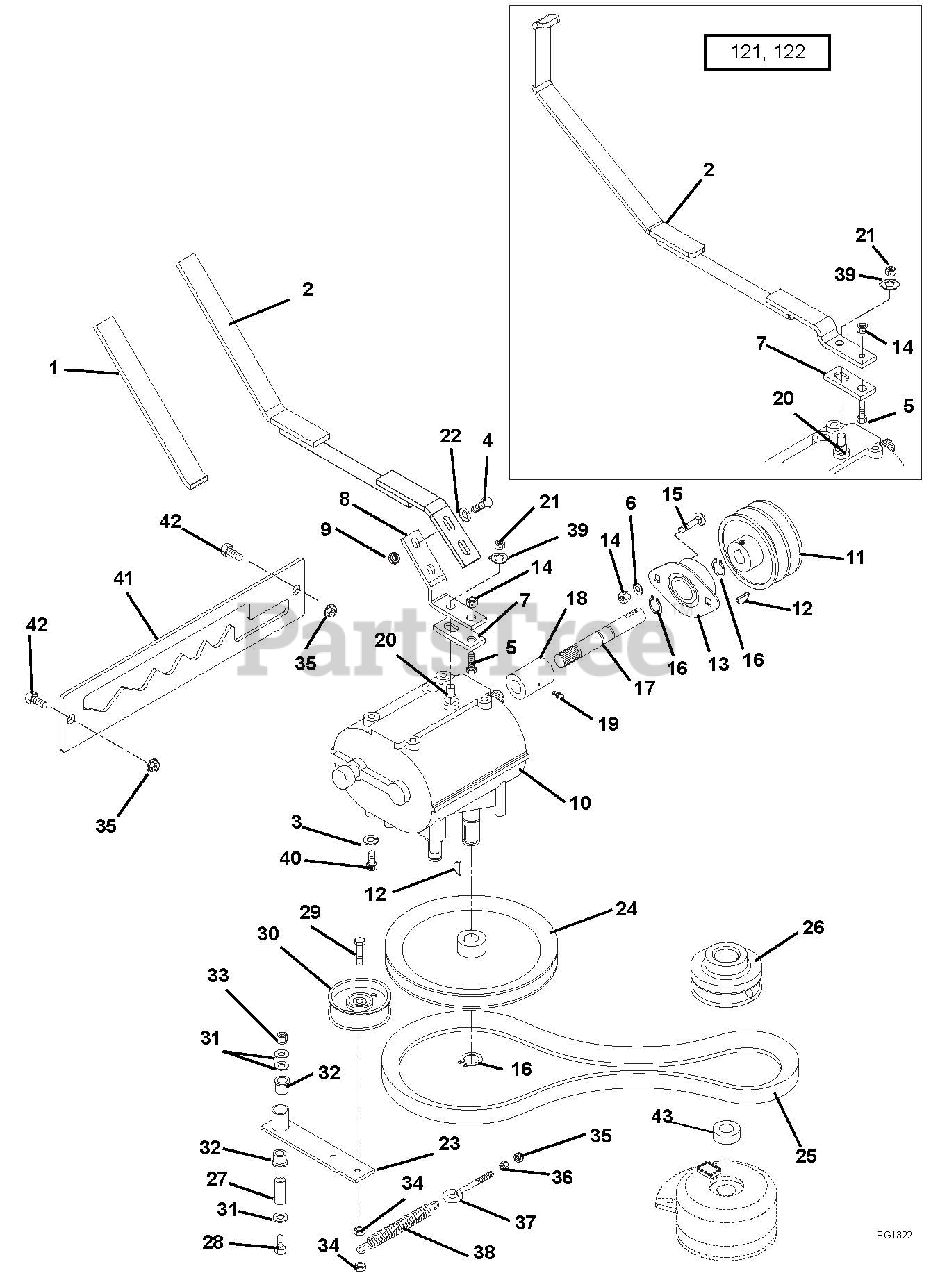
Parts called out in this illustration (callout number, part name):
1	Grip
2	Lever, Shift
3	Washer-Locking .31 x .078 Regular
4	Bolt-Hex .31-18 x 1.00 Grade 5
5	Bolt-Hex .25-20 x 1.00 Grade 5
6	Washer-Flat-Steel .25 x .562 x .049
7	Plate, Shift
8	Arm, Shift
9	Nut-Locking-Top-Flange .31-18
10	Transmission
11	Sheave, Drive
12	Key-Woodruff .19 x .75
13	Bearing-Flange .625 x 1.875 x .797
14	Nut-Locking-Nylon .25-20
15	Bolt-Round Head Square Neck .25-20 x .75 Grade 5
16	Ring-Retaining-External .579 x .930
17	Shaft, Half
19	Fitting, Lube, .25-28
20	Switch-Neutral Start N.O.
21	Nut-Locking-Center .38-24
22	Washer-Flat-Steel .344 x .688 x .065
23	Weldment, Ground Drive Idler
24	Pulley-V 7.50 x .63 Sheave Transmission
24	Pulley-V 7.50 x .626
25	V-Belt 4L-Section 33.9
26	Sheave, Clutch
27	Bushing, Steel .56 x .745 x 2.04
28	Bolt-Hex .50-13 x 3.25 Grade 5
29	Bolt-Hex .38-16 x 2.00 Grade 5
30	Idler-Pulley Flat 3.25 x .625
31	Washer-Flat-Steel .531 x 1.06 x .095
32	Bushing-Flange Nylon .762 x 1.00 x .58 x 1.48
33	Nut-Locking-Nylon .50-13
34	Nut-Locking-Jam-Center .375-16
35	Nut-Locking-Nylon .38-16
36	Nut-Hex .38-16
37	Eye Bolt
38	Spring, Extension
39	Washer, Locking .38 x .13
40	Bolt-Hex .31-18 x .75 Grade 5
41	Plate, Shift Lever Detent
42	Bolt-Hex .38-10 x 1.00 Grade 5
43	Bushing, Spacer 1.032 x 1.25 x .25 Promaster
